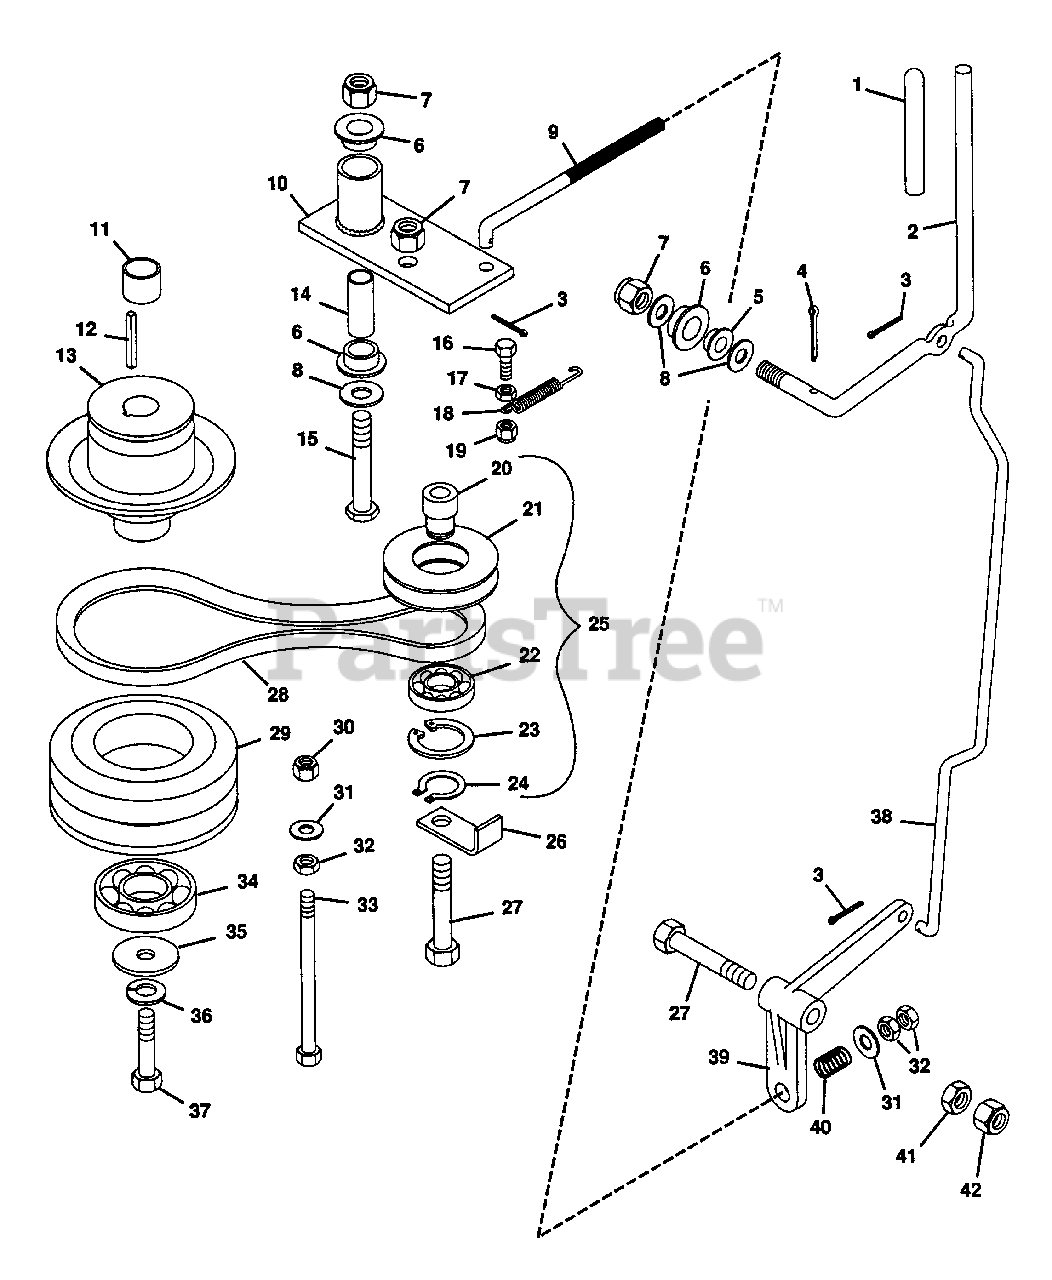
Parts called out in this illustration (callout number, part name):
1	GRIP, PTO LEVER
2	LEVER, PTO ACTUATING
3	PIN, COTTER .09X.75
4	PIN, COTTER .187X1.625
5	BUSH., FLG. .515X1.00X.745 NY.
6	BUSH., FLG. .764X1.47X.560 NY.
7	NUT, LOCK 1/2-13
8	WASHER, FLAT .531X1.250X.100
9	ROD, PTO CLUTCH ACTUATING
10	WELDMENT, PTO IDLER
11	SPACER, MANUAL START
12	KEY, SQUARE .250X2.375
13	WELDMENT, PTO CLUTCH HUB
14	BUSH., ST. .560X.745X2.04 STL.
15	BOLT, HEX 1/2-13X2.75 SPECIAL
16	BOLT, HEX 5/16-18X1.00
17	NUT, HEX 5/16-18
18	SPRING, PTO RETURN
19	NUT, LOCK 5/16-18
20	BUSH., FLG. .515X.787X1.41 STL.
21	SHEAVE, IDLER
22	BEARING, BALL
23	RING, RETAINING
24	RING, RETAINING
25	ASSEMBLY, IDLER SHEAVE
26	GUIDE, BELT
27	BOLT, HEX 1/2-13X2.50
28	V-BELT, PRO PTO
29	SHEAVE, MOWER CLUTCH
30	NUT, LOCK 3/8-16
31	WASHER, FLAT .406X.812X.065
32	NUT, HEX 3/8-16
33	BOLT, HEX 3/8-16X4.00
34	BEARING, BALL 1.574X3.149X.708
35	WASHER, SPECIAL
36	WASHER, LOCK 7/16 REG.
37	BOLT, HEX 10 MMX1.5
38	ROD, PTO CONTROL
39	LEVER, PTO CLUTCH
40	SPRING, COMP. 1X.78X338 LB/IN
41	NUT, HEX 1/2-13
42	NUT, LOCK 1/2-13
